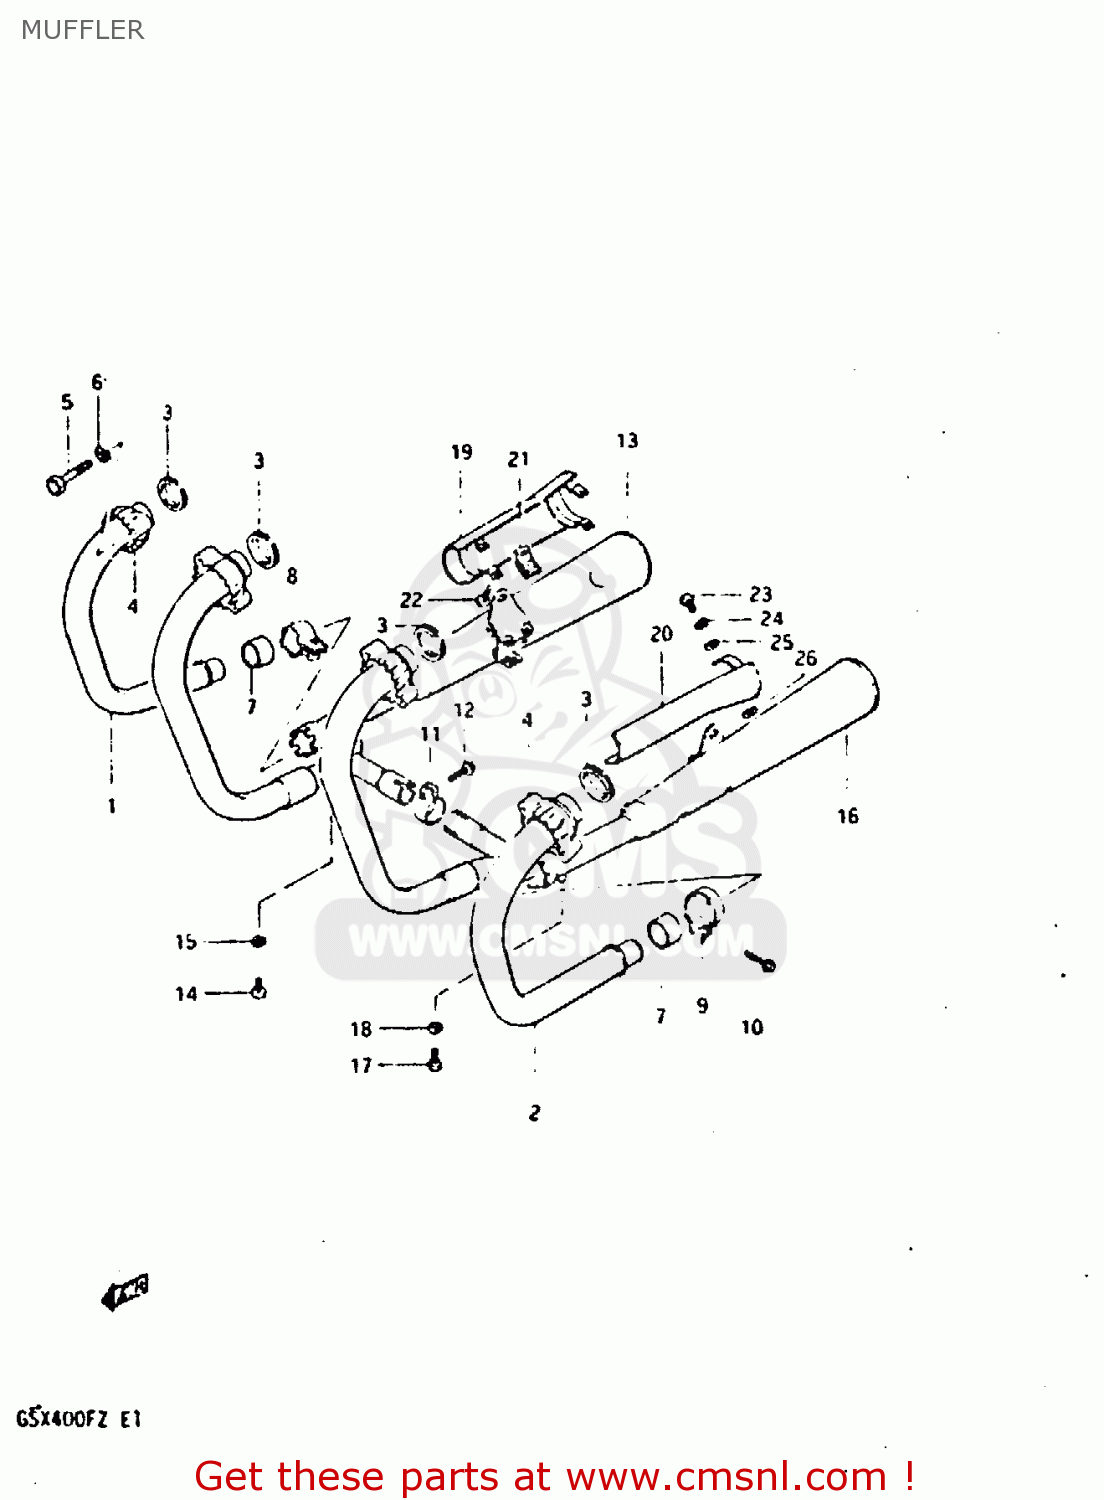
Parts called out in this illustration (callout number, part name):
1	PIPE, EXHAUST RH
2	PIPE, EXHAUST LH
3	GASKET,EXHAUST PIPE (NAS)
4	CLAMP,EXHAUST PIPE
5	BOLT 8X40
6	LOCK WASHER
7	CONNECTOR,MUFFLER
8	CLAMP,MUFFLER CONNECTOR
9	CLAMP,MUFFLER CONNECTOR
10	BOLT
11	CLAMP,EXHAUST COUPLER
12	BOLT,REAR
13	MUFFLER, RH
14	BOLT
15	WASHER
16	MUFFLER, LH
17	BOLT
18	WASHER
19	COVER, MUFFLER RH
20	COVER, MUFFLER LH
21	CLAMP
22	SCREW
23	SCREW
24	LOCK WASHER
25	WASHER
26	GASKET
